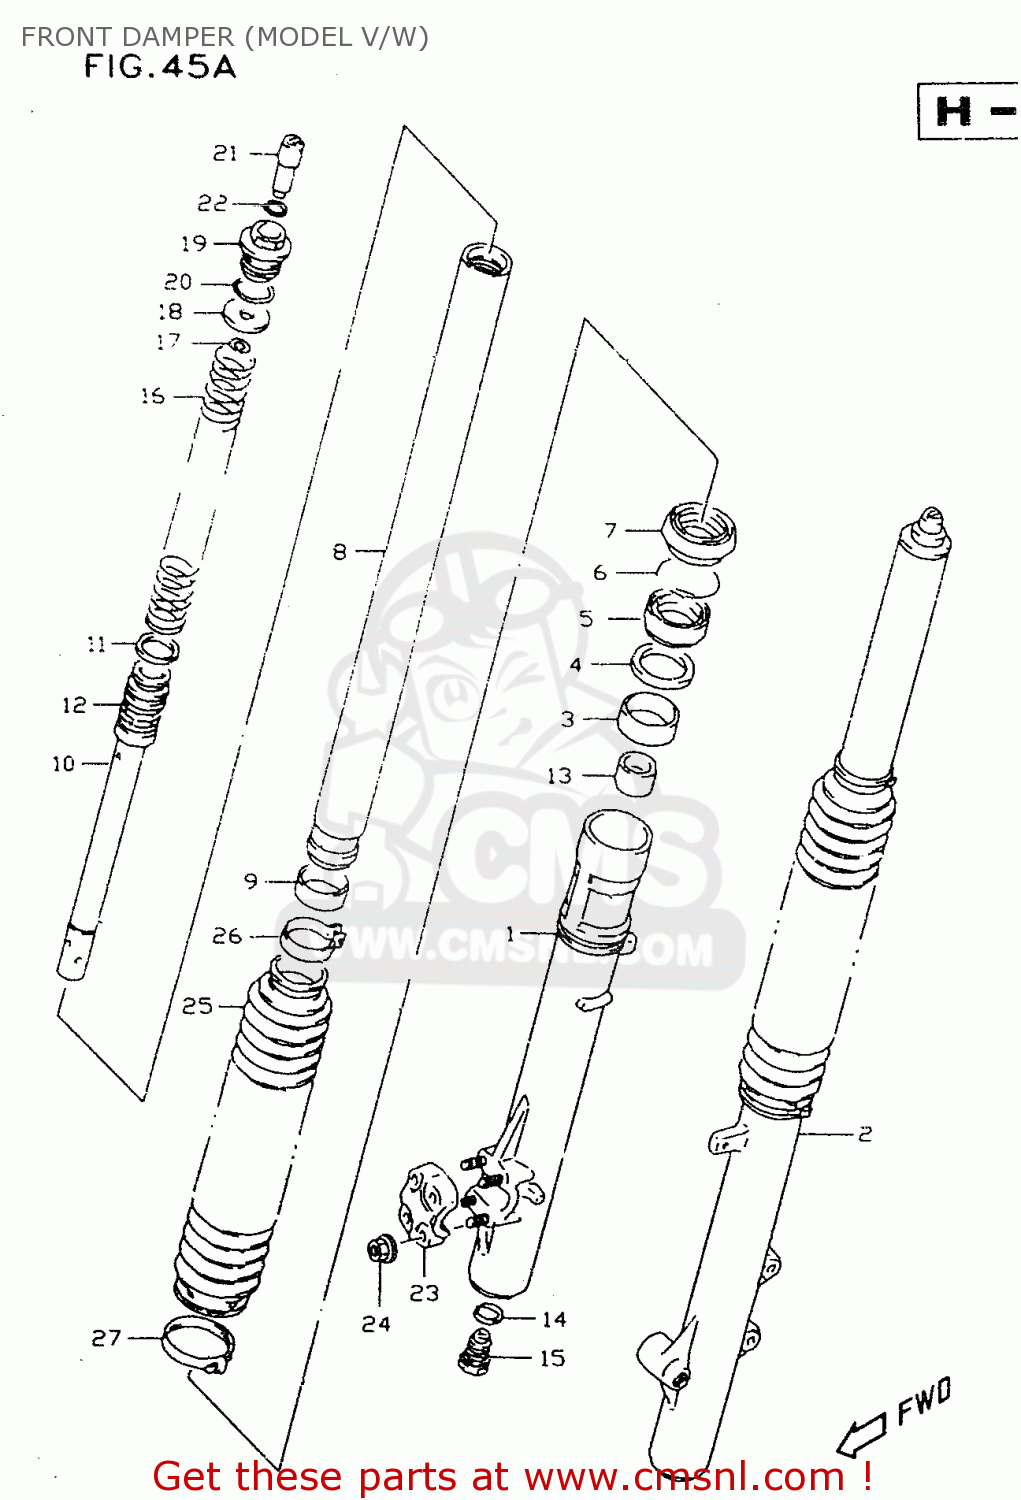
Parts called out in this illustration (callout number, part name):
1	TUBE,OUTER,RIGHT
2	TUBE,OUTER,LEFT
3	BUSH,GUIDE
4	SPACER,SEAL
5	SEAL,OIL
6	CIRCLIP,FORK OIL SEAL
7	DUST SEAL
8	TUBE,INNER
9	BUSH,SLIDE
10	CYLINDER
11	RING,PISTON
12	SPRING,REBOUND
13	PIECE,OIL LOCK
14	GASKET (NAS)
15	BOLT,PIECE
16	SPRING,MAIN
17	E RING
18	SEAT,SPRING
19	BOLT,FORK
20	O RING
21	ADJUSTER,SPRING
22	O RING
23	HOLDER,AXLE
24	NUT,HOLDER
25	BOOT
26	BAND,BOOT UPR
27	BAND,BOOT LWR
